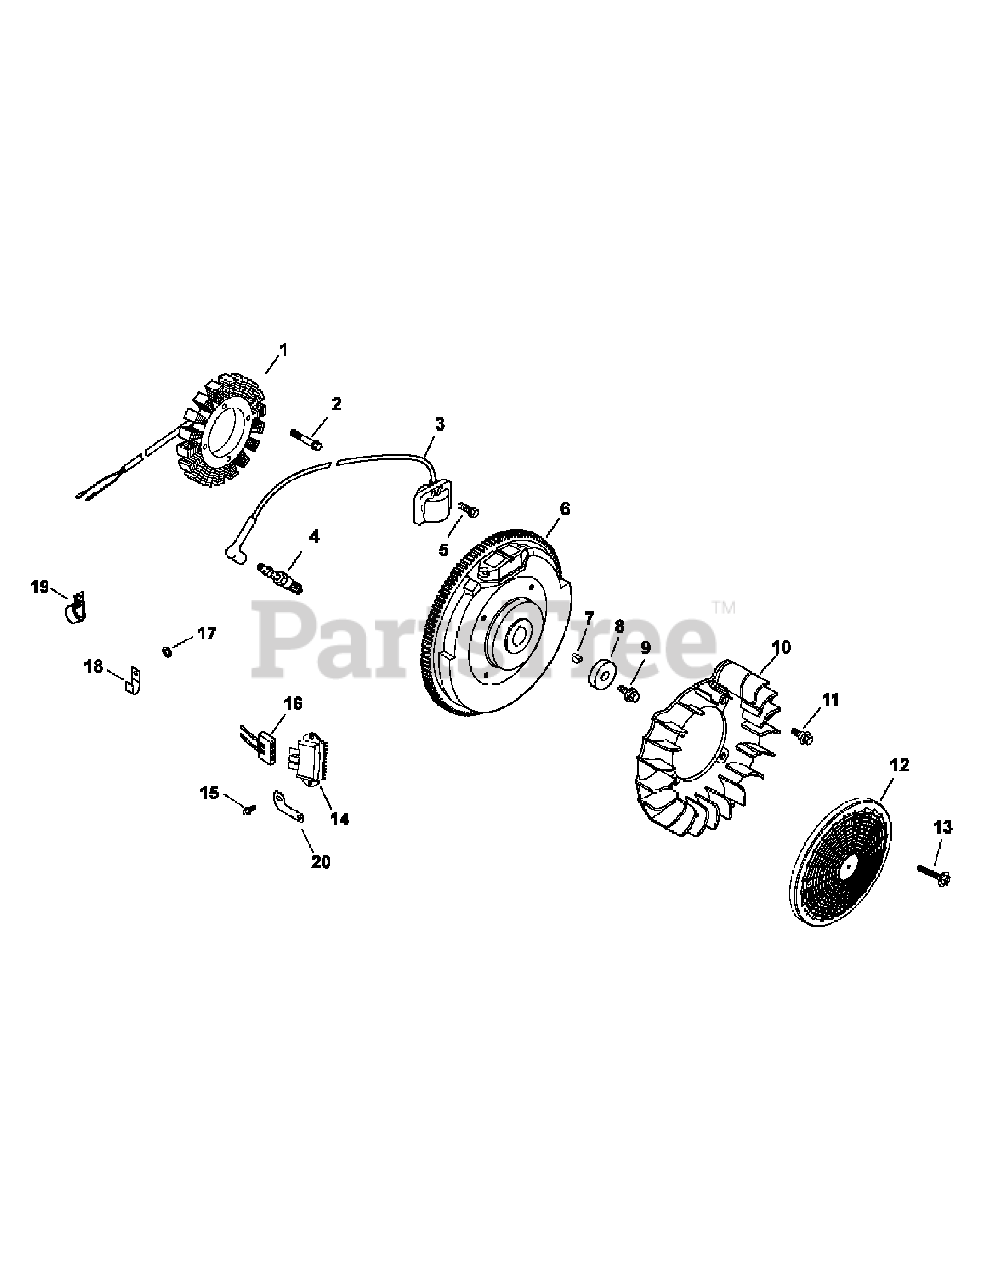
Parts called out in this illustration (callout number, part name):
1	Flange Screw, M8 x 1.25 x 45
2	Oil Seal, 2.38 x 1.45
3	Square Head Pipe Plug, 3/8
4	Oil Pan Assembly
5	Governor Gear Shaft
6	Governor Regulating Pin
8	Governor Gear Kit
9	Oil Pick-Up O-Ring
11	Oil Pump Assembly
12	Oil Feed Tube (Filter to Oil Pan)
13	Oil Feed Tube Assembly
15	Oil Filter Nipple
17	Oil Pressure Switch
18	Oil Feed Tube
